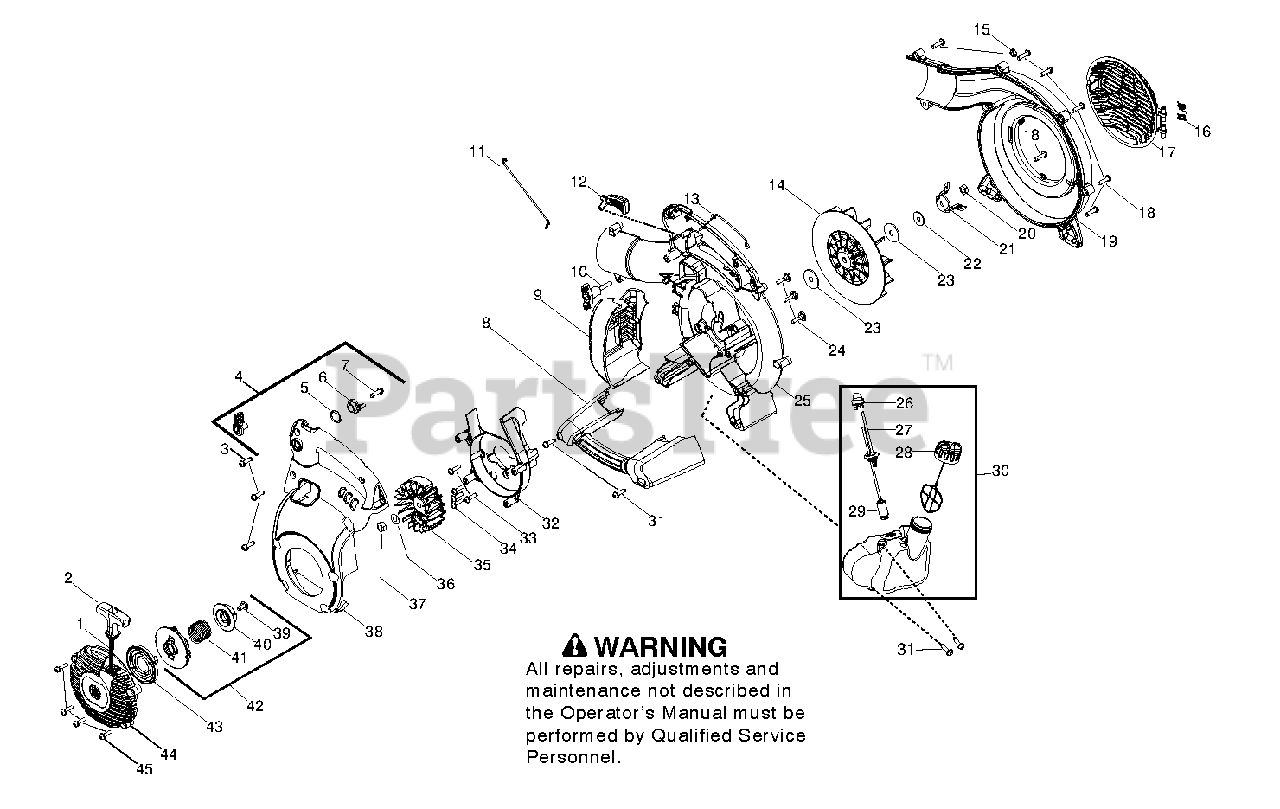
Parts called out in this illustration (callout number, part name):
2	HANDLE - STARTER
4	KIT - CRUIS CONTROL (5,6,7)
6	RATCHET CRUISE CONTROL
8	HANDLE - ASSIST
9	ASSY - MUFFLER GUARD
10	ASSY - TUBE CLAMP
11	WIRE LINKAGE
12	TRIGGER - THROTTLE
13	WIRE, HANDLE GROUND
16	SPRING, VAC DOOR
20	NUT, IMPELLER
21	MULCH BLADE
22	WASHER-FLYWHEEL
23	WASHER IMPELLER
24	SCREW FUEL TANK RETAINER
26	AIR PURGE
27	KIT FUEL LINE GROMMET
28	ASSY - FUEL CAP W/RETAINER
29	FUEL PICK-UP ASSY
30	ASSY - FUEL TANK 26,27,28,29
32	SCROLL, FLYWHEEL
34	SCREW - SHROUD
35	ASSY, FLYWHEEL
36	WASHER FLAT
37	NUT-FLYWHEEL
41	SPRING EPS2
42	KIT - STARTER
43	SPRING STARTER
44	HOUSING - STARTER COVER
45	SCREW - SHROUD
